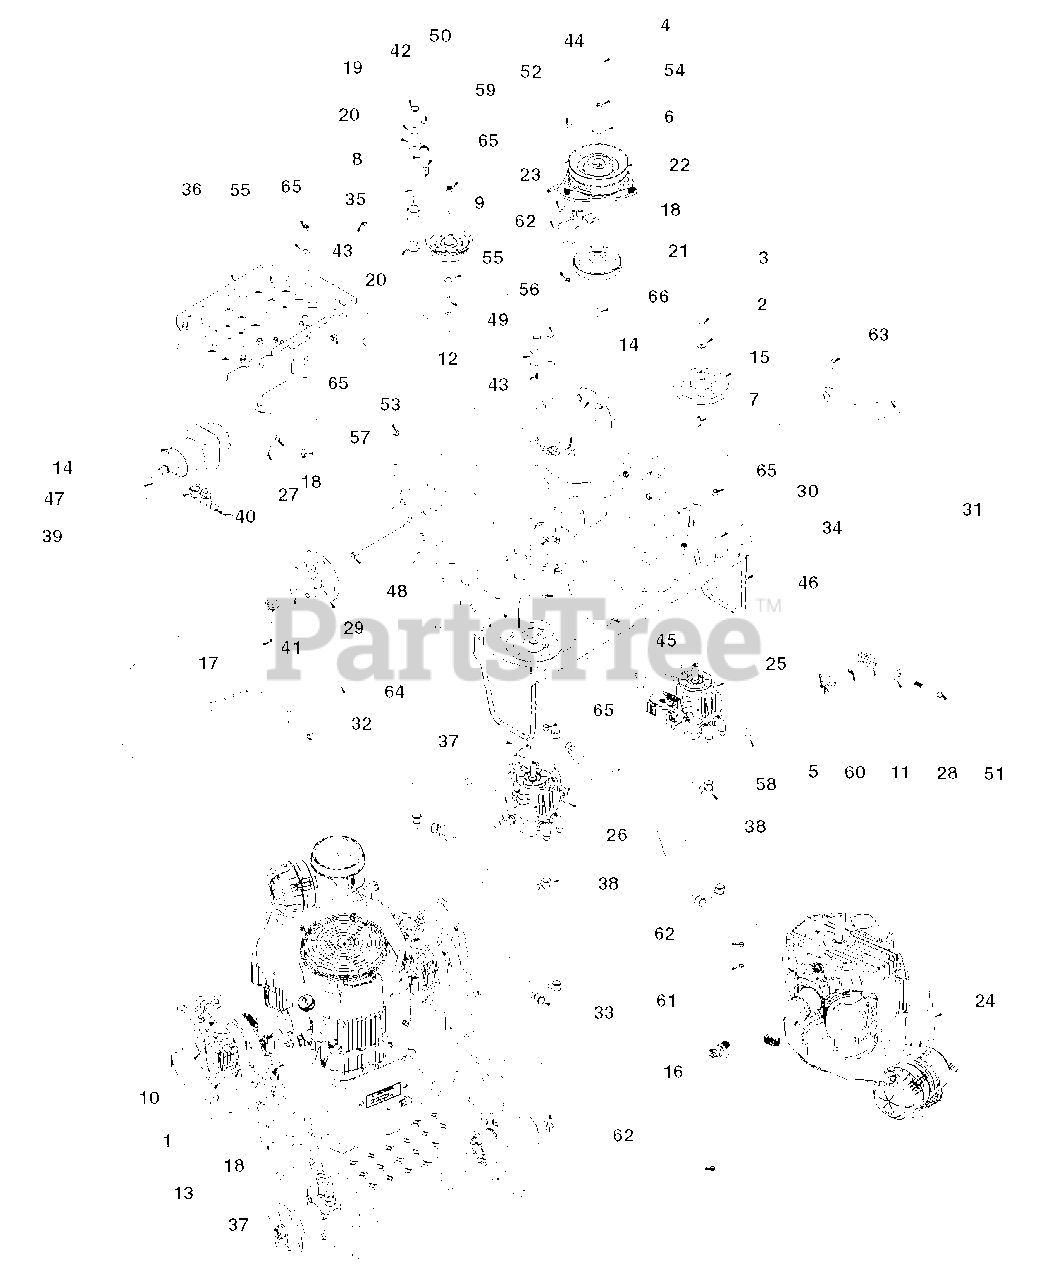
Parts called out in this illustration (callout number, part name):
1	Hose, 3/8 SAE30r7 Fuel & Oil
2	Washer, .250 Wide Heavy Flat Y
3	Bolt, M6 x 1.00 x 10 Hex 8.8 Y
4	Bolt, 7/16-20 x 3.00 Hex 5 Y
5	Switch (N.0.)
6	Spacer, .468 x 1.38 x .375 Y
7	Key, M5 x M5 x M30 RD
8	Spring, Ext .900 x .135x4.50 Y
9	Pulley, V-belt 4.00x.379 w/Bearing
10	Clamp, Hose - 1/2" Pinch
11	Spring, Com 1.22x.162x2.50 Y
12	Weldment, Pivot Idler Mount
13	Fitting, Tun 3/8 Hose
14	Motor, Wheel HGM-12p-7172
15	Assembly, Pump Pulley w/Set Screw
16	Fitting, Oil Drain
17	Pin, Cot .125 x 2.00 EXTP Y
18	Tie Wrap, Black
19	Bushing, Machine .750 x 1.25 x .048
20	Bearing, Flange .750 x 1.000 x .750 x 1.250
21	Pulley, V-belt 4.78pd x 1.000
22	Clutch Assembly, Ogura
23	Plate, Clutch Dog
24	Engine, Kawasaki 19hp FH580V
25	Assembly, Hyd Pump
26	Assembly, Hyd Pump
27	Cover, Operator Presence Control
28	Washer, Spring Y
29	Assy, Rear Wheel Hub
30	Belt, HA 68.2 EL AMD OHR
31	Weldment, RH Brake Arm
32	Weldment, LH Brake Shaft
33	Hose, Hyd 1/2 x 26 1/2 Ezflex
34	Weldment, Frame 34 w/Decals
35	Weldment, Idler Pivot
36	Assy, Foot Plate
37	Abrasion Sleeve
38	Adapter, .75 FESW x 3/4MJICX90
39	Adapter, Hydraulic Steel 7/8 "O" To .75
40	Adapter, 8MJ-10MB90
41	Shim, .020 x .787 x 1.102
42	Ring, Retaining-External .750 x .042
43	Grease Zerk, .25-28 Straight .69 LG
44	Bolt, Hex .31-18 x .75 Grade 5
45	Bolt, Hex .31-18 x 1.50 Grade 5
46	Bolt, Hex .31-18 x 1.75 Grade 5
47	Key, Woodruff .1875 x .75
48	Bolt, 3/8-16 x 1.00 Hex 5
49	Bolt, 3/8-16 x 1.75 Hex 5
50	Bolt, 3/8-16 x 2.50 Hex 5
51	Bolt, 3/8-16 x 3.25 Hex 5
52	Bolt, 7/16-14 x .750 Hex 5
53	Nut-Hex .31-18
54	Washer, .375 Medium Spring Lock Y
55	Washer-Flat-Steel .438 x 1.00 x .083
56	Bolt, Round Head Square Neck .38-16x1.00 G 5
57	Bolt, Round Head Square Neck .38-16x1.00 G 5
58	Bolt, Round Head Square Neck .38-16x1.25 G 5
59	Nut, .38-16 Jam Grade 5
60	Nut-Locking-Nylon 10-24 with Insert
61	Nut-Jam .312-18
62	Nut-Locking-Nylon .312-18
63	Pin-Roll .156 x 1.00
64	Screw, Machine 10-24 x .625 Panhead
65	Nut-Locking-Nylon .38-16
66	Key, .250 x .250 x .995 TPR
